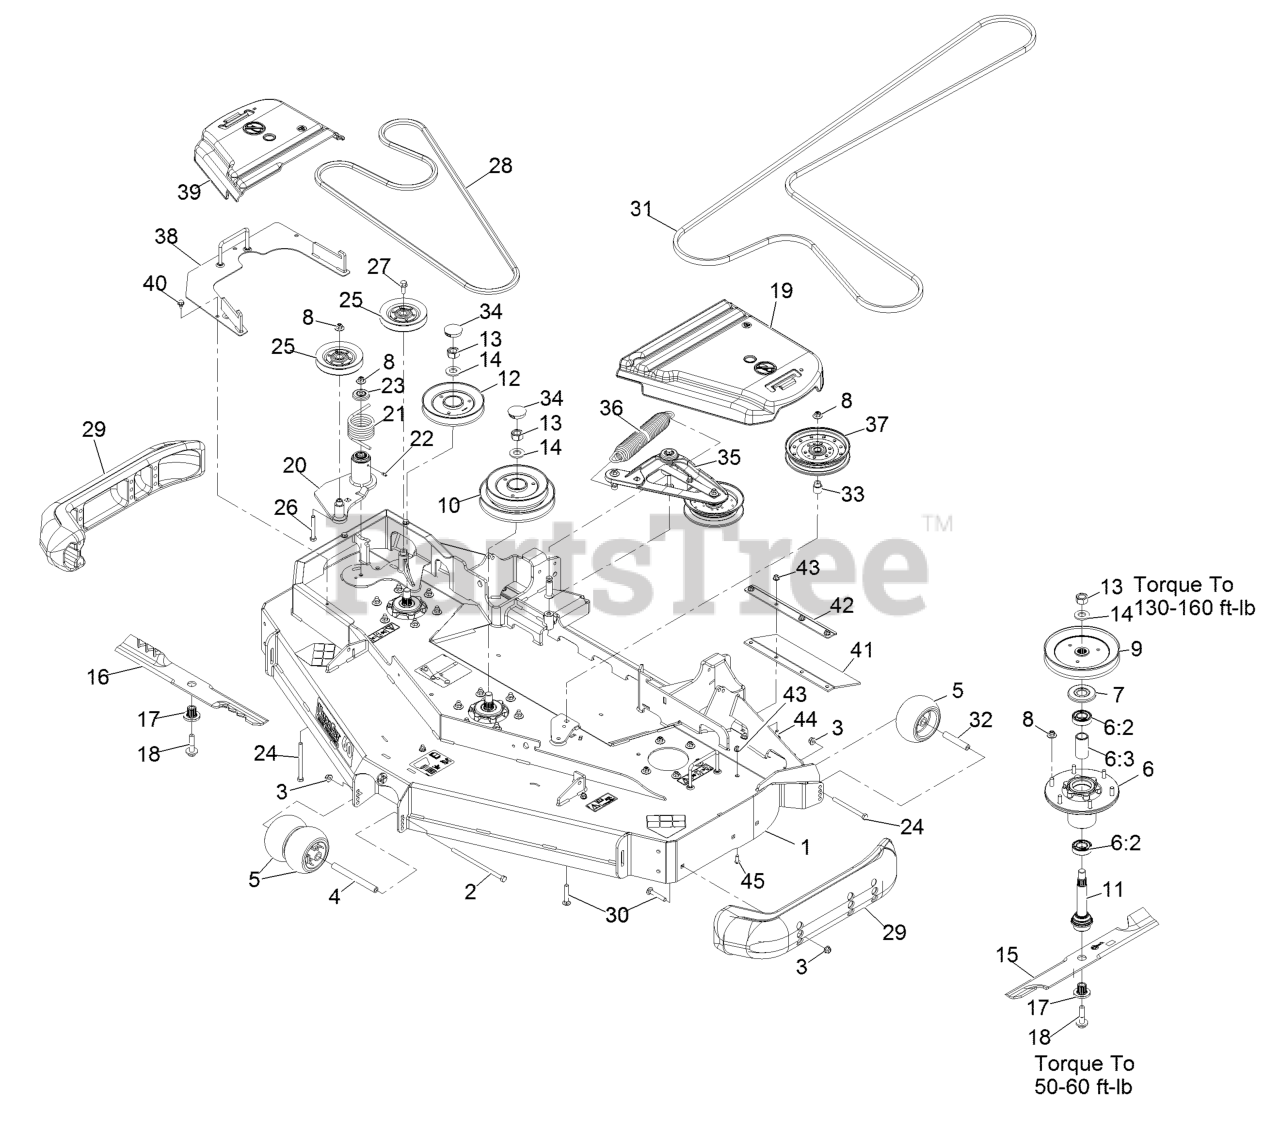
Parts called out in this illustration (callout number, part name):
1	DECK-RD60 NLZ, W/DECALS
2	SCREW-HH
3	NUT-HF, NI
4	SPACER-WHEEL
5	ROLLER-SCALP, ANTI
6	ASM-CUTTER HSG WITH BEARINGS
6:2	BEARING-BALL
6:3	SPACER-BEARING
7	GUARD,BEARING TOP .989
8	Nut-Nyloc 3/8-16 Flg
9	SHEAVE,BLADE DRIVE 7.25
10	SHEAVE, DOUBLE 60RD
11	ASM-SPINDLE AND SEAL
12	SHEAVE-RD REV DRIVE SERIE
13	NUT-HEX
15	Blade-Extreme 2, 20.50"
16	Blade-Low Lift 20.5, Rd60
16	Blade-Extreme 2-20.50, Rd60
17	BUSHING,SPLINED
18	SCREW,SEMS 1/2-20 X 2.19
19	COVER-BELT, LH
20	IDLER ASM
21	SPRING-TORSION
22	FITTING-GREASE
23	GUARD-TOP
24	SCREW-HH
26	SCREW-HH
27	SCREW-HHF
28	BELT
29	SKID-BUMPER, DECK
30	Bolt-Carriage 3/8-16 X 2 1/4
31	BELT
32	TUBE-SPANNER
33	BUSHING-IDLER
34	PLUG,BLACK NYLON 1.75
35	DECK IDLER ASM
36	SPRING-EXTENSION
38	COVER-DRIVE REVERSE
39	COVER-BELT, RH
41	GUARD-TIRE
42	SUPPORT-OUTER FLAP
43	NUT-HF, NI
44	SCREW-CARR
45	SCREW-HSBH
